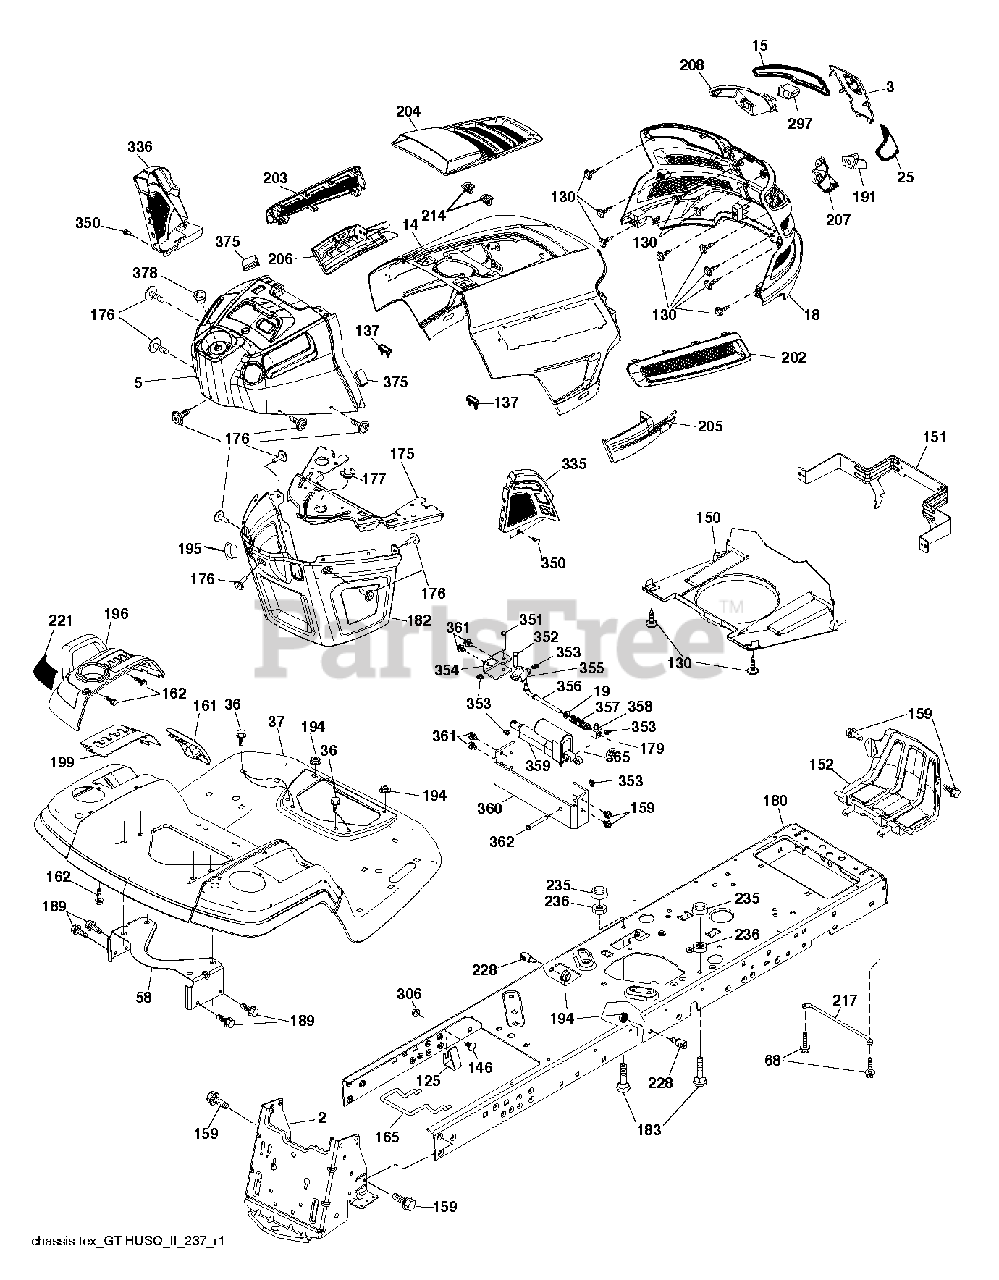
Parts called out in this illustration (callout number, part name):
2	DRAWBAR.STGT
3	APPLIQUE.SUBASM.GT.HUSQ.II
5	DASH.TEX.GT2.UPPER
14	HOOD.ASM.HUSQVARNA.GT.TEX.422
15	LENS.HEADLIGHT.LH.GTII.2011
18	GRILLE.SUBSTRATE.2011.
19	WASHER
25	LENS.HEADLIGHT.RH.GTII.2011
36	SCREW 5/16"
37	FENDER.PNT.TX.GT.CH/FW/DL.HUSQ
58	BRKT.SUPPORT.FNDR/TANK
68	SCR 5/16-18 X 1/2 SELFTAP ZN
125	CLIP.FUEL.LINE
130	SCREW.#10 X 0.750.BOS
137	BUMPER DASH
146	BOLT.RDHD.SHT.SQNK.3/8-16X5/8
150	AIR.DUCT.GTV.BLACK
151	BRACKET.PIVOT.HOOD.GT.HUSQ.II
152	SHIELD.BROWNING.PNT.GT.V2
159	SCREW, 3/8-16X3/4
161	CONSOLE.WINDOW.FUEL.HUSQ.GT
162	SCREW.HI-LO.CONSOLE
165	SUPPORT.TANK.REAR.B/TE
175	Crossmember Plate
176	SCREW.#10-24X5/8.RN.QU
177	BUSHING STEERING
180	CHASSIS.LT/GT.BOLTED
182	DASH.LOWER.COMMON.12V.ADAPTOR
183	BOLT.5/16-18X1-1/4 FULL THD
189	SCREW
191	INSERT.REFLECTIVE.RH.HUSQ.GTII
194	NUT LOCK HEX FLANGE 5/16-18
195	PLUG.HOLE.DASH.LOWER.12V.BLK
196	CONSOLE.ASM.DECKLIFT.HUSQGT.DL
199	PLATE.DECK.LIFT.HUSQVARNA.GT
202	VENT.SIDE.RH.GT.HUSQ.II.
203	VENT.SIDE.LH.GT.HUSQ.II.498
204	VENT.TOP.HUSQ.GT2
205	SIDE.TRIM.RH.GT.HUSQ.II
206	SIDE.TRIM.LH.GT.HUSQ.II.GRAY
207	BEZEL LIGHT.RH.GT.II.MYLAR
208	BEZEL LIGHT.LH.GT.II.MYLAR
214	CLIP.RETAINER.TINNER.
217	ROD.PIVOT.HOOD
221	REFLECTOR.LH.TEX GT HU
228	STUD.FASTNER.W/ANTI-ROTATE
235	SPACER FENDER
236	NUT.CENTERLOCK.5/16-
297	INSERT.REFLECTIVE.LH.HUSQ.GTII
306	NUT LOCK FLG 3/8-16 UNC
335	COVER.LOWER.DASH.RH.BLACK
336	COVER-LH.LOWER.DASH.GT2.BLACK
350	CLIP.X-MAS.TREE
351	PIN.CLEVIS.375X2.125
352	PIN.CLEVIS.(.375 X 1.25)
353	CLIP RETAINER
354	SUPPORT.BELLCRANK
355	BELLCRANK.PIVOT.LOCK.DIFF
356	LINK.LOCK.DIFF
357	SPRING.COMPRESSION
358	GUIDE.SWIVEL
359	ACTUATOR.ELECTRIC
360	BRACKET.ACUATOR
361	SCREW LT.3/8-46X5/8
362	PIN.CLEVIS.(.375 X 2.42)
365	SPACER.NYLON.75" X .4375
375	BUMPER CLIP-ON. DASH 1"
378	BUSHING FLANGE; PLASTIC
